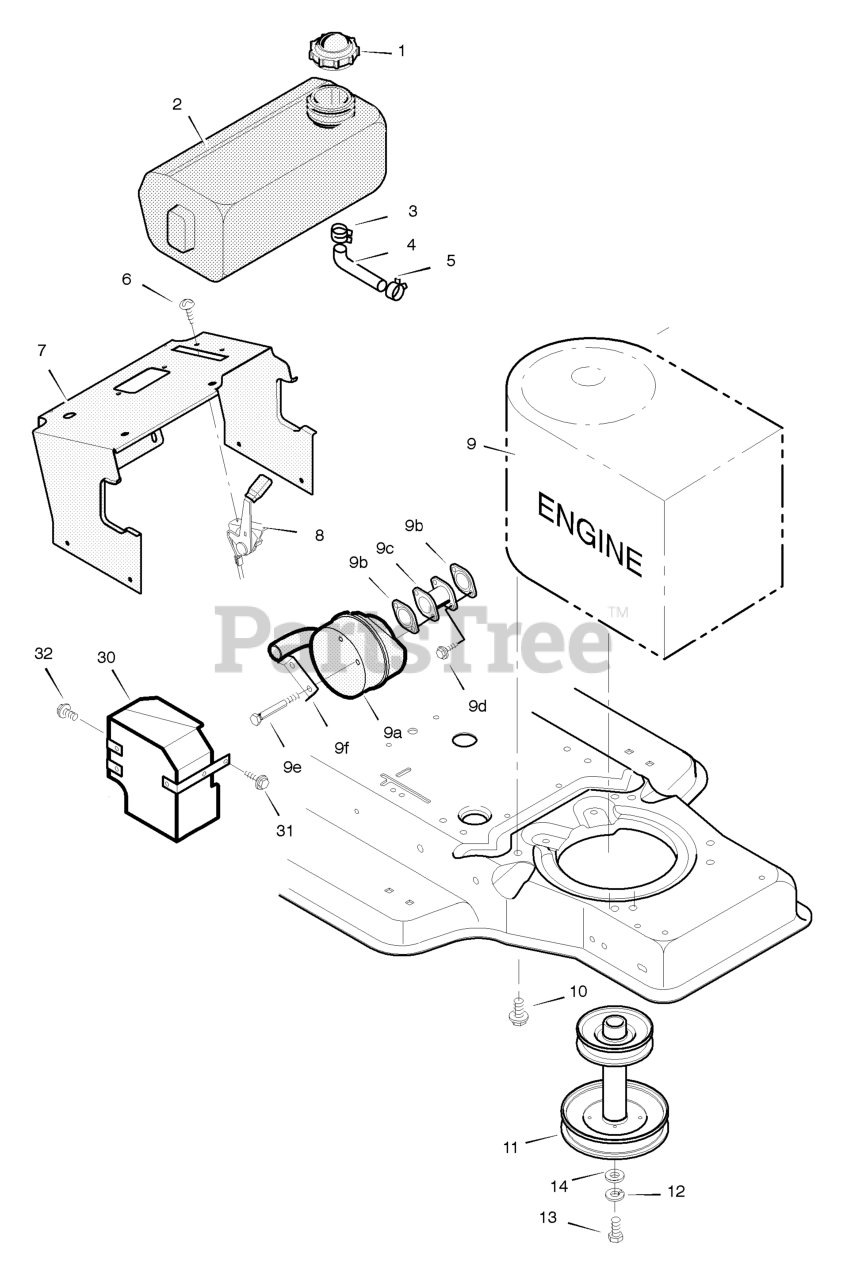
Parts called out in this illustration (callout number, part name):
1	Fuel Cap
2	Fuel Tank
3	Hose Clamp
4	Fuel Line (Must cut to length)
5	Hose Clamp
7	Support, Dash
8	Throttle Control
9	Engine *
9B	GASKET, Exhaust
9C	Adapter, Muffler
9D	Screw, Adapter
9E	Bolt, Muffler
9F	Lock, Screw
10	Bolt, Engine Mount
11	Stack Pulley Assembly
12	Lockwasher
13	Bolt, Hex
30	Shield, Heat
